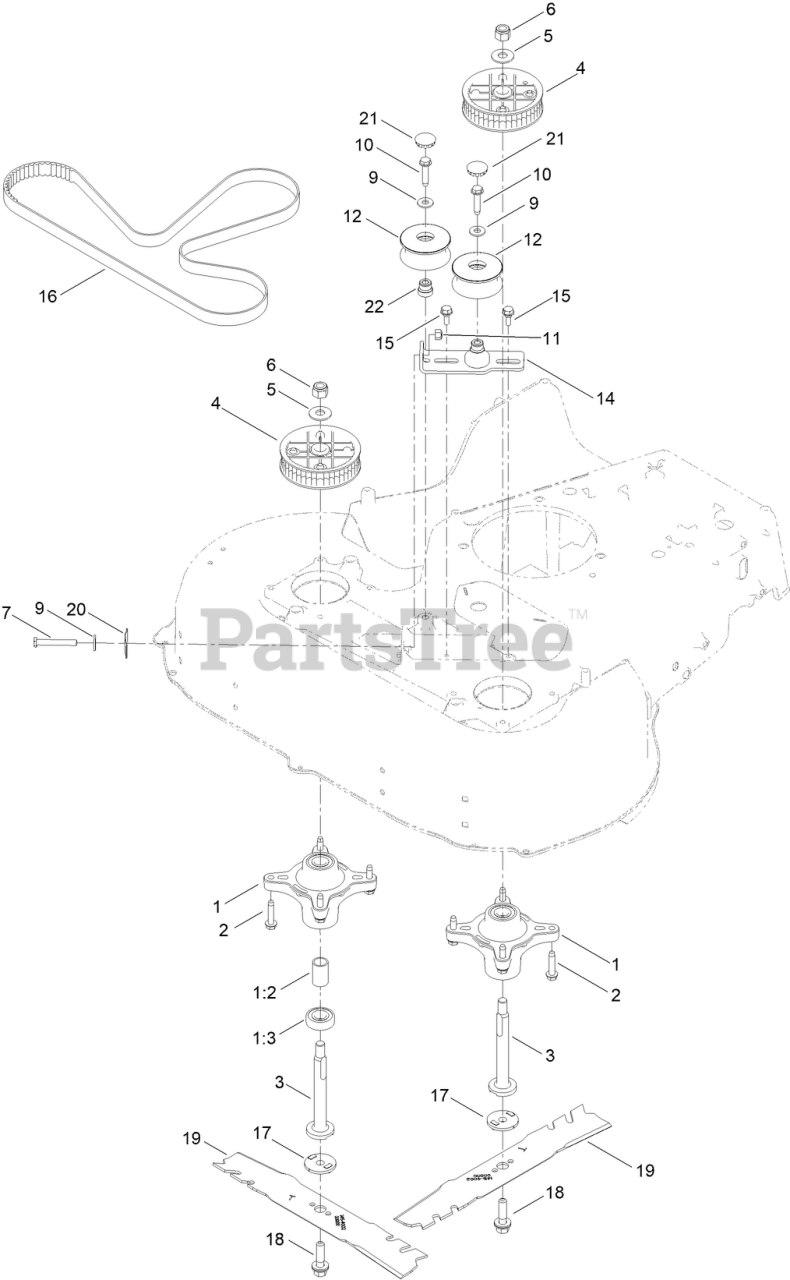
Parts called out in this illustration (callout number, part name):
1	SPINDLE ASM
1:3	BEARING-BALL
2	SCREW-THD ROLL, HWH
3	SHAFT-SPINDLE
4	SPROCKET
5	WASHER-SPRING
6	NUT-HEX
7	BOLT-TAP, HH
9	WASHER-FLAT
11	NUT-LOCK, NI
12	PULLEY-IDLER, FLAT
12	PULLEYS AND IDLER KIT
14	BRACKET-IDLER
15	SCREW-SHOULDER,HWH
16	BELT-SYNCHRONOUS
17	ADAPTER-BLADE
18	BOLT-BLADE
19	BLADE-ROTARY
20	SPRING-FLAT
21	PLUG-BUTTON
22	ADAPTER-BORE
